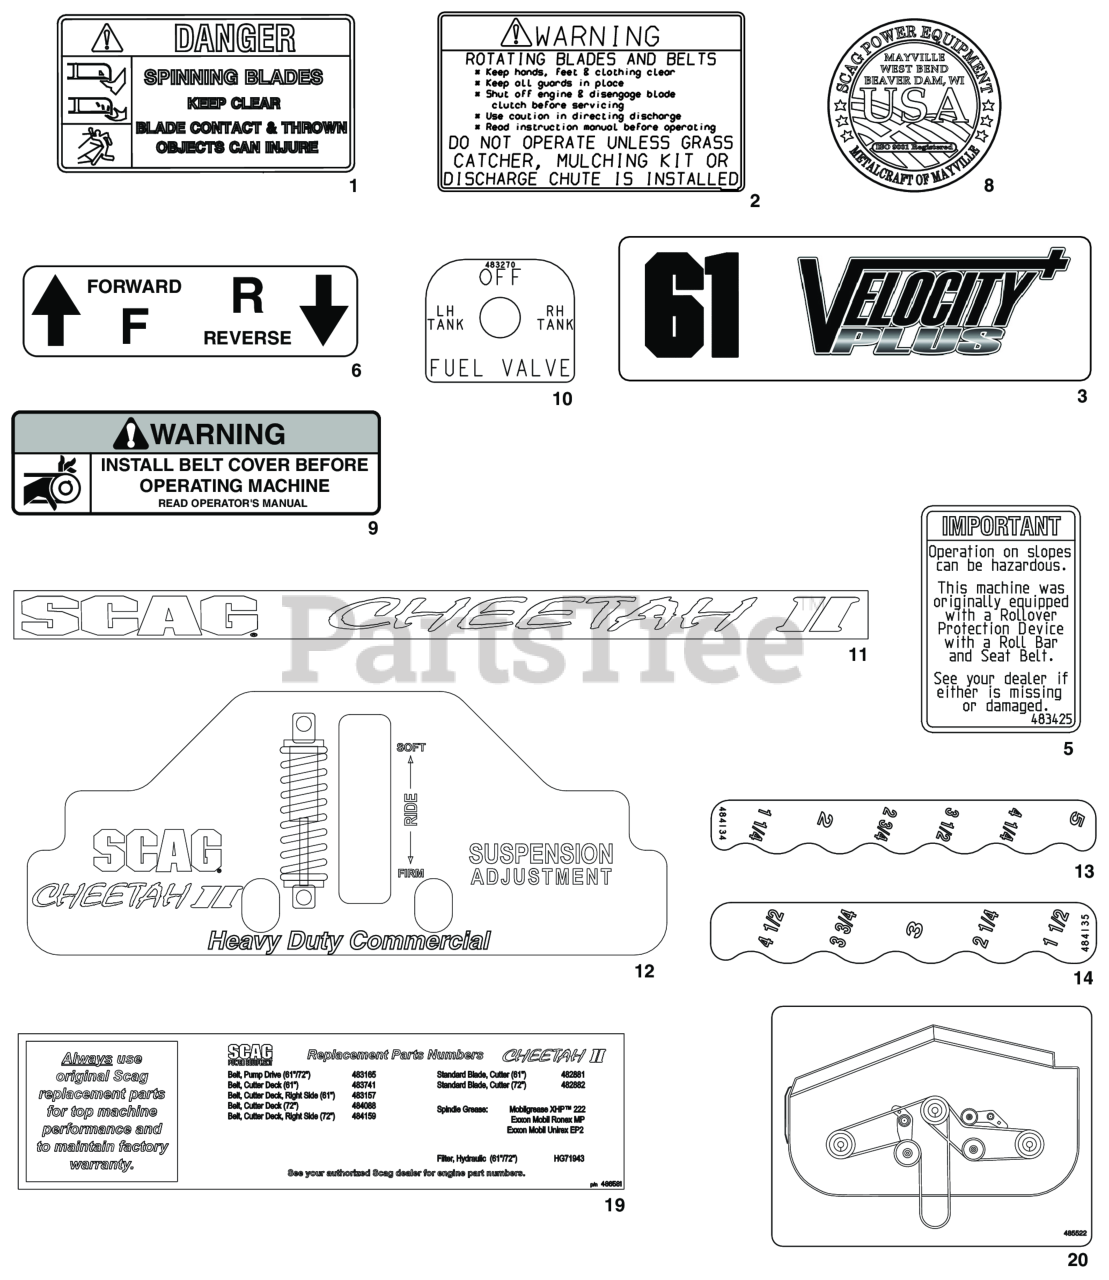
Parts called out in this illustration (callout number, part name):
1	Decal, Danger-Spinning Blades
2	Decal, Warning - Rotating Blades
3	DECAL, VELOCITY PLUS - 61
3	Decal, Velocity Plus - 61RD
3	Decal, 72" Velocity Plus
5	Decal, ROPS
6	Decal, Traction Control
8	Decal, Metalcraft - USA
9	Decal, Warning - Belt Cover
10	Decal, Fuel Shut Off
11	Decal, Scag Cheetah II
12	Decal, Suspension Adjustment
13	Decal, Deck Height - LH
14	Decal, Deck Height - RH
19	Decal, SCZII Replacement Parts
20	Decal, Belt Routing (61V)
20	Decal, SCZII Belt Routing 61RD
